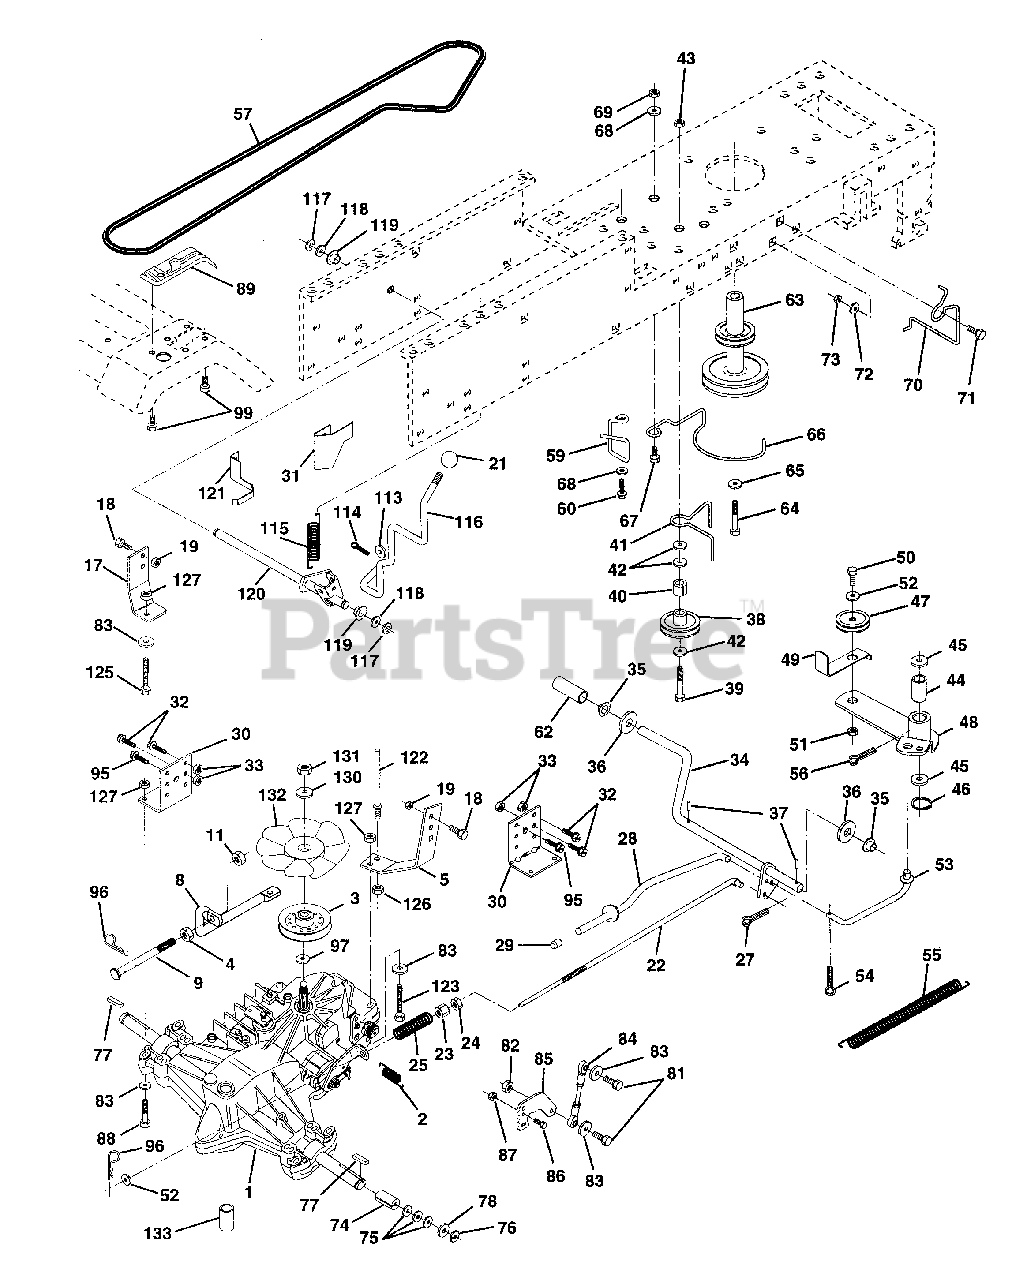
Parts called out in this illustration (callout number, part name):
1	Transaxle Assembly
2	Spring, Return, Brake
3	Pulley, Transaxle
4	Nut Hex Jam 5/16-18 Unc
5	Strap Torque Rh Hydro 18/20" T
8	Control Bypass Hydro 18" Tires
9	Rod Bypass Hydro 18/20"
11	Nut Lock Hex W/Ins 5/16-18 Unc P
17	Strap Torque Lh Hydro 18/20" T
18	Bolt Fin Hex 3/8-16 Unc x 1 Gr. 5
19	Nut Lock Hex W/Wsh 3/8-16 Unc
21	Knob 1/2-13
22	Rod, Brake Hydro
23	Nut
24	Locknut
25	Spring, Brake Rod
27	Pin Cotter 1/8 x 3/4 CAD.
28	Rod, Parking Brake
29	Cap, Parking Brake
30	Bracket, Transaxle
31	Keeper Belt Lh
32	Bolt Hex Hd 5/16-18 Unc x 3/4
33	Nut Lock Hex W/Ins. 5/16-18 Unc
34	Shaft, Foot Pedal
35	Bearing, Nylon
37	Pin, Roll
38	Pulley, Idler, Flat
40	Spacer, Split
41	Keeper, Belt Retainer
42	Washer 13/32 x 13/16 x 12 Gauge
43	Nut
44	Bearing, Nylon
45	Washer, Hardened
46	Ring, Klip
47	Pulley, Idler, V-Groove
48	Bellcrank Assembly
49	Retainer, Belt
50	Bolt
52	Washer
53	Link, Clutch
54	Pin
55	Spring, Return, Clutch
56	Pin
57	V-Belt, Ground Drive
59	Keeper, Center Span
60	Screw Thdrol. 3/8-16 x 3/4 Ty. TT
62	Cover, Pedal
63	Pulley, Engine
64	Bolt, Hex
65	Washer
66	Keeper Belt Engine
67	Bolt
68	Washer 13/32 x 13/16 x 12 Gauge
70	Keeper Belt Engine
71	Bolt Hex 3/8-16 x 1
72	Washer 13/32 x 1-1 /4 x 12 Gauge
73	Nut Crownlock 3/8-16
74	Spacer, Split
75	Washer 25/32 x 1-1/4 x 16 Gauge
77	Key, Square
78	Washer 25/32 x 1-5/8 x 16 Gauge
81	Bolt Fin Hex 5/16-18 Unc x 1-1/4
82	Nut Lock Hex W/Ins. 5/16-18 Unc P
83	Washer 11/32 x 3/4 x 16 Ga.
84	Rod, Tie Hydro 18" Tires
85	Arm, Control Hydro
86	Screw Cap Hex 5/16 x 18 x 1
87	Nut Lock Hex W/Ins: 5/16-18 Unc P
88	Bolt Fin Hex 5/16-18 Unc
89	Console, Shift
95	Screw, Thdroll. 3/8-16 x 1 Type TT
96	Retainer Spring 1" Zinc/Cad
97	Washer 21/32 x 1 x 16 Ga.
113	Washer 17/32 x 3/4 x 16 Ga.
114	Pin Cotter 1/8 x 1 CAD
115	Spring Torsion T/A
116	Rod Shift Hydro LT
117	Ring Klip #5304-62
118	Washer 21/32 x 1-1/4 x 16 Ga.
119	Bushing Rod Strig. 629/632 ID
120	Shaft Asm. Cross Hydro 20" Tires
121	Keeper Belt Lh Hydro 0750. 18/20"
122	Keeper Belt Rh Hydro 0750. 18/20"
123	Bolt Fin Hex 5/16-18 x 2-1/4
125	Bolt Fin Hex 5/6-18 Unc x 1-1/2
126	Nut Keps Hex 3/8-16 Unc
127	Nut Lock Hex W/Ins 5/16-18 Unc P
130	Washer Beliville .501 D x 1.50D
131	Nut Nylon Insert 1/2-20 Unf.
132	Fan, Hydro 7"
133	Line Fuel Hydro 4"
